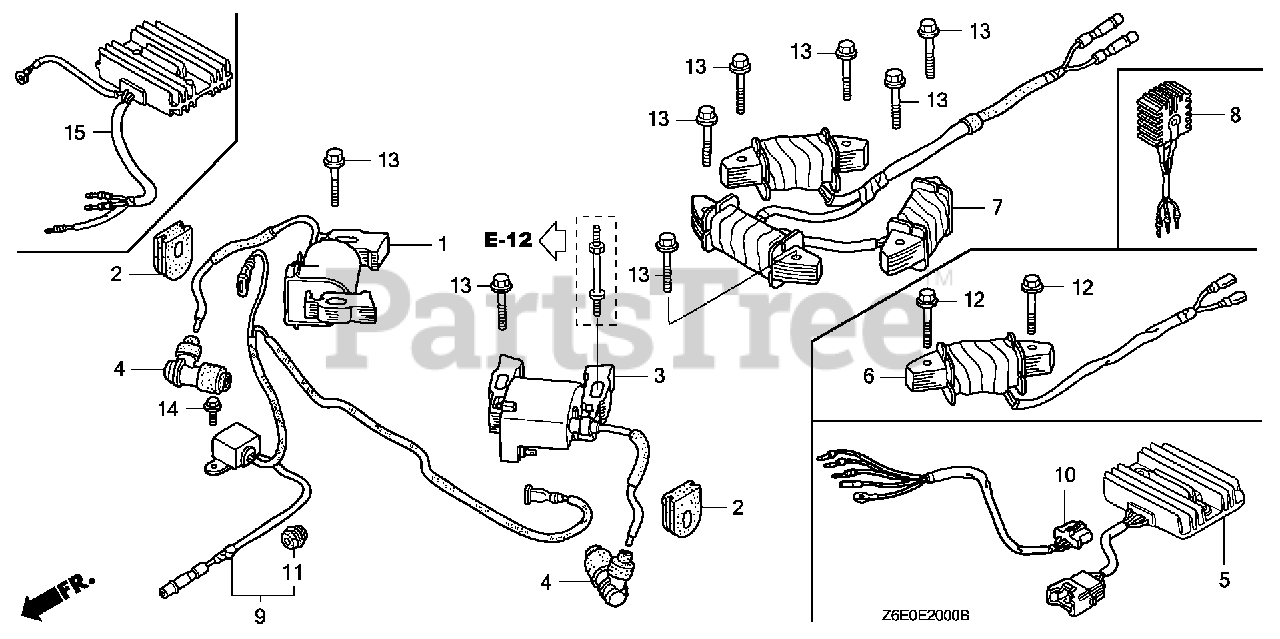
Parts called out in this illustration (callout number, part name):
1	COIL ASSY., IGNITION (200MM) (BLACK) (R. SIDE)
2	GROMMET, IGNITION WIRE
3	COIL ASSY., IGNITION (215MM) (GRAY) (L. SIDE)
4	CAP ASSY., NOISE SUPPRESSOR
7	COIL ASSY., CHARGE (12V/20A)
9	DIODE ASSY., ENGINE STOP
11	GROMMET, TOOL
13	BOLT, FLANGE (6X32) (CT200)
14	BOLT, FLANGE (6X8)
